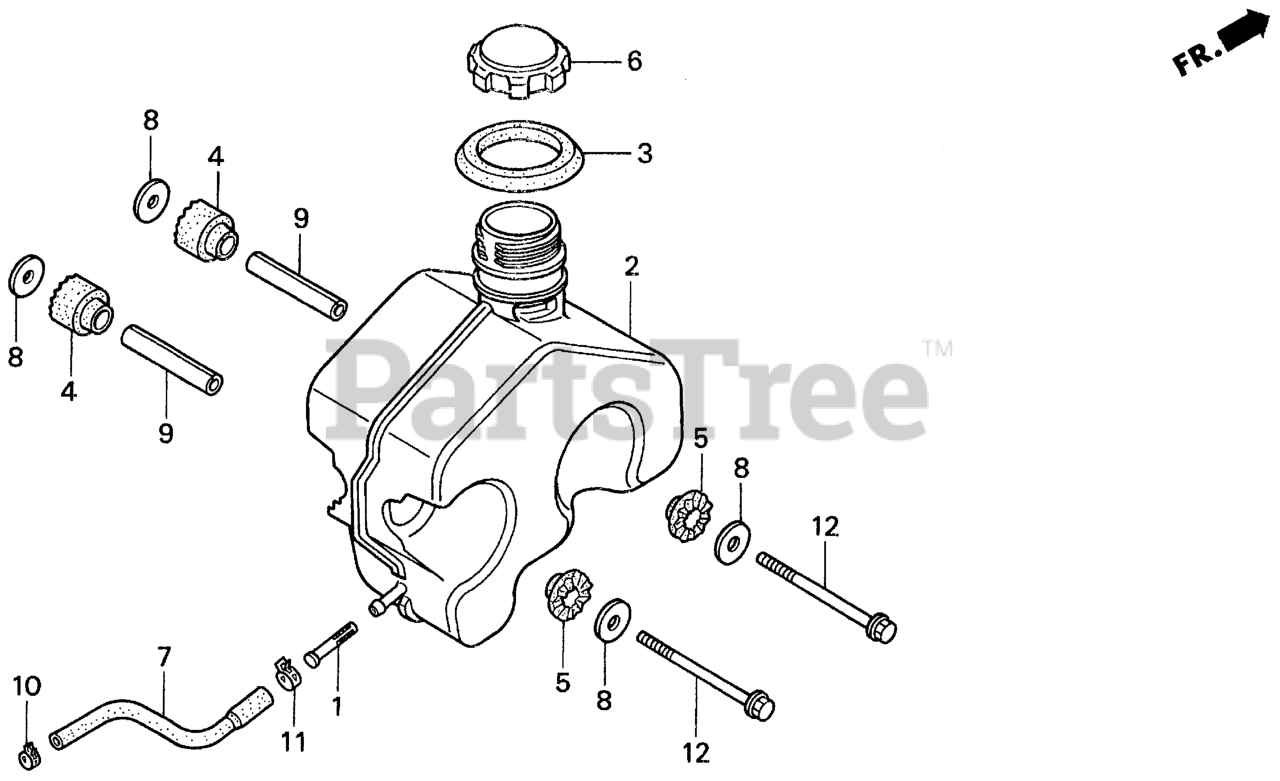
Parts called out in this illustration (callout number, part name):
1	FILTER, FUEL
2	TANK, FUEL
3	SEAL, FUEL FILLER NECK
4	RUBBER B, TANK MOUNTING
5	RUBBER B, TANK MOUNTING
6	CAP ASSY., FUEL TANK
7	TUBE, FUEL
8	WASHER (8MM)
9	COLLAR, TANK SET
10	CLIP, TUBE (D8)
11	CLAMP, TUBE (D10)
12	BOLT, FLANGE (8X105)
